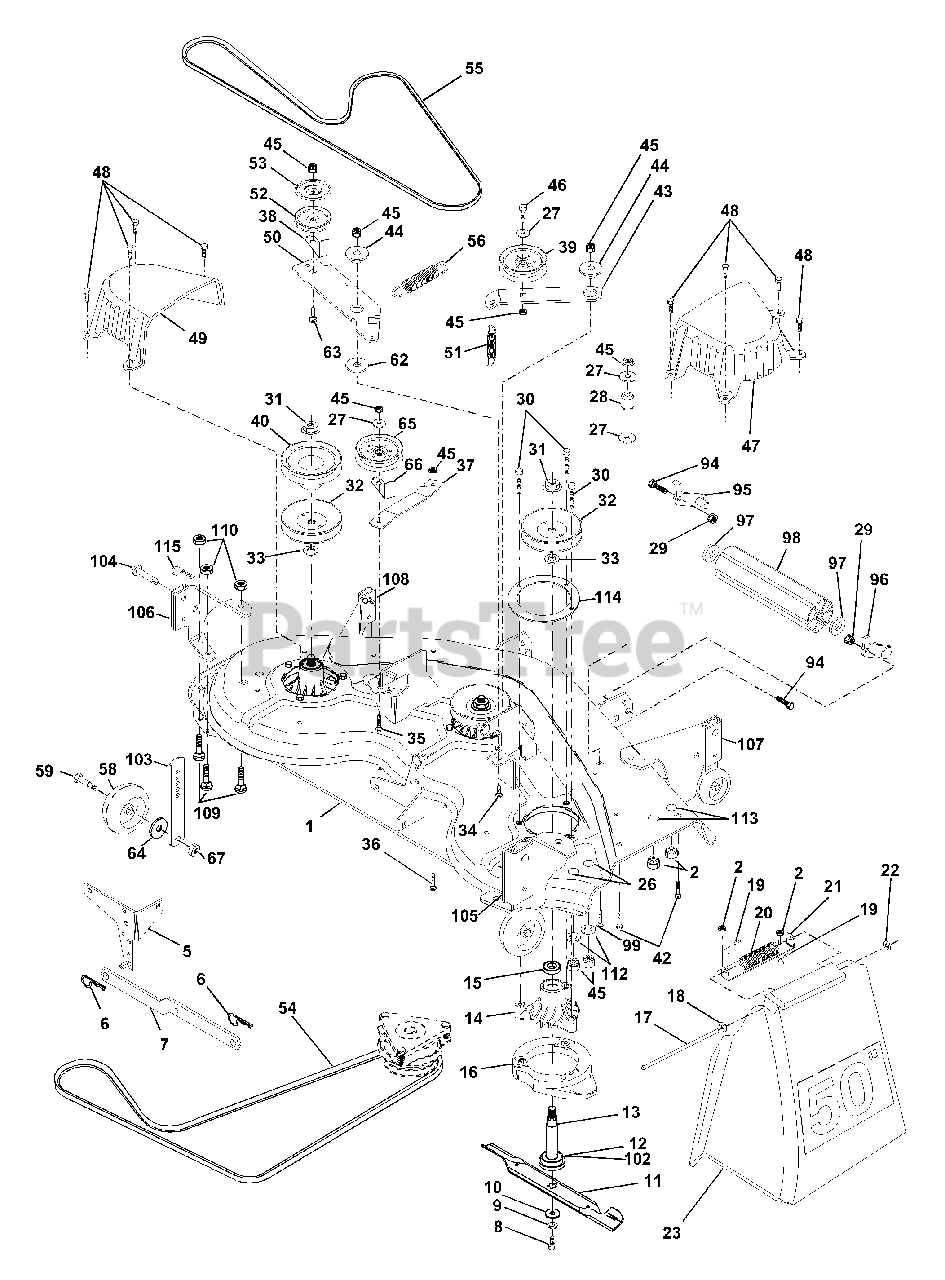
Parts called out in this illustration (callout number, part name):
1	Deck Asm., Mower 50" Vented
2	Nut, Crownlock 5/16-18 Unc
5	Bracket Asm., Sway Bar
6	Retainer, Spring
7	Arm Suspension, Rear
8	Bolt 3/8-24 x 1.25 Gr. 8 Patched
9	Washer, Lock Hvy 3/8 Unplated
10	Washer, Hard Blade Mower Vented
11	Blade
12	Bearing, Ball #6204 (Mandrel)
13	Shaft Asm., W/Lower Brg
14	Housing, Mandrel 50" Vent
15	Bearing, Ball Mandrel
16	Stripper, Mower Vented
17	Rod, Hinge
18	Washer 11/32 x 5/8 x 16 Ga.
19	Cap, Sleeve
20	Spring, Torsion Deflector
21	Bracket, Deflector
23	Shield, Deflector Mower
26	Bolt Rdhd Sht Sqnk 3/8-16 x 3/4
27	Washer 13/32 x 13/16 x 16 Ga.
28	Spacer, Spring Stop Idler
29	Nut, Lock Hex W/Wsh 3/8-16 Unc
30	Screw Tdhrolling Washer Head
31	Nut, Flg Top Lock Cntr 9/16
32	Pulley, Mandrel
33	Washer, Spacer Mower Vented
34	Bolt, Carriage 3/8-16 x 1-1/4
35	Bolt, Carriage 3/8-16 x 2
36	Bolt, Carriage 3/8-16 x 1 Gr. 5
37	Stiffener, Arm Idler
38	Keeper, Belt Idler
39	Pulley, Idler Flat
40	Pulley, Driven
42	Bolt, Carriage 5/16-18 Unc x 3/4
43	Arm, Idler Secondary
44	Spacer, Retainer
45	Nut, Crownlock 3/8-16 Unc
46	Bolt, Fin Hex 3/8-16 Unc x 1-3/4
47	Cover, Mandrel RH
48	Screw, Thd Roll 1/4-20 x 5/8
49	Cover, Mandrel LH
50	Arm, Idler Primary
51	Spring, Secondary
52	Pulley, Idler V Groove
53	Shield, Idler
54	V-Belt, Mower Primary
55	V-Belt, Mower Secondary
56	Spring, Primary
58	Wheel, Gauge
59	Bolt, Shoulder
62	Washer Hardened
63	Bolt Carriage 3/8-16 x 1-1/2
64	Washer 3/8 x 7/8 x 14 Ga.
65	Pulley Idler Flat Mower
66	Keeper, Belt Idler 44/50" Vent
67	Nut, Center Lock 3/8-16
94	Bolt, Fin Hex 3/8-16 UNC x 1
95	Bracket, Asm. Noseroller LH
96	Bracket, Asm. Noseroller RH
97	Washer 17/32 x 7/8 x 16 Ga.
98	Roller, Nose
99	Bolt, Carriage 3/8-16 x 1-3/4 Gr. 5
102	Washer Felt
103	Bar Pnt Adjusting Wheel Gauge
104	Pin Head Rivet
105	Bracket Whl Ga. Asm Rear RH 50"
106	Bracket Whl Ga. Asm. Rear LH 50"
107	Bracket Whl Ga. Asm. Front RH 50"
108	Bracket Whl Ga. Asm Front LH 50"
109	Bolt Carriage 5/16-18 x 5/8 Blk
110	Nut Crownlock 5/16-18 Blk
112	Washer 17/32 x 3/4 x 16 Ga.
113	Bolt Carriage 5/16-UNC x 1/2
114	Reinforcement Mandrel Ring
115	Retainer Spring Blk D
